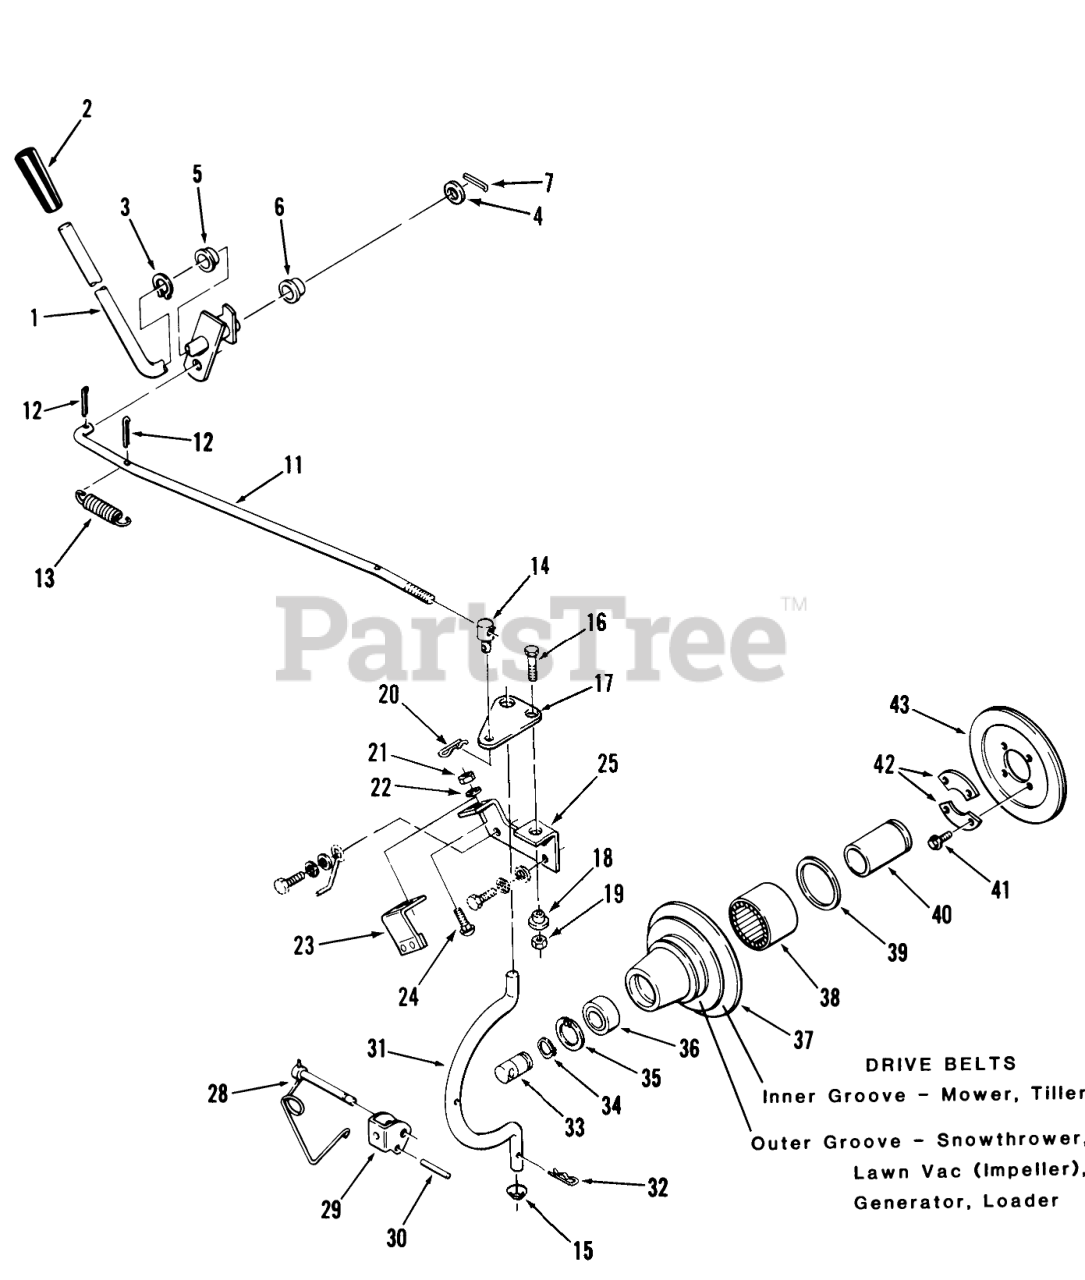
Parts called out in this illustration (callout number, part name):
1	PTO Clutch Lever
2	GRIP
3	Grip Ring
4	SHIM-WASHER
5	BUSHING-NYLINER
6	NYLINER BUSHING
7	Pop Rivet
11	PT0 Clutch Rod
12	Pop Rivet
13	SPRING
14	TRUNNION
15	RING-REINFORCED CIRC
16	BOLT
17	PTO Plate
18	SPACER-LIFT LINK
19	Nut
20	Hairpin Cotter
21	Nut
23	PTO Brake Assy
24	Bolt-Carriage
25	BRACKET
28	Pin
29	Clevis
31	ROD-HOUSING
32	Hairpin
33	SHAFT-PTO
34	RING-SNAP, EXTERNAL
35	Ring-Snap
36	BEARING-BALL
37	Housing-Clutch
38	BRG-NEEDLE OPEN END
39	SEAL-OIL
40	RACE-BEARING
41	H H C S
42	RETAINER
43	Clutch Plate & Facing
